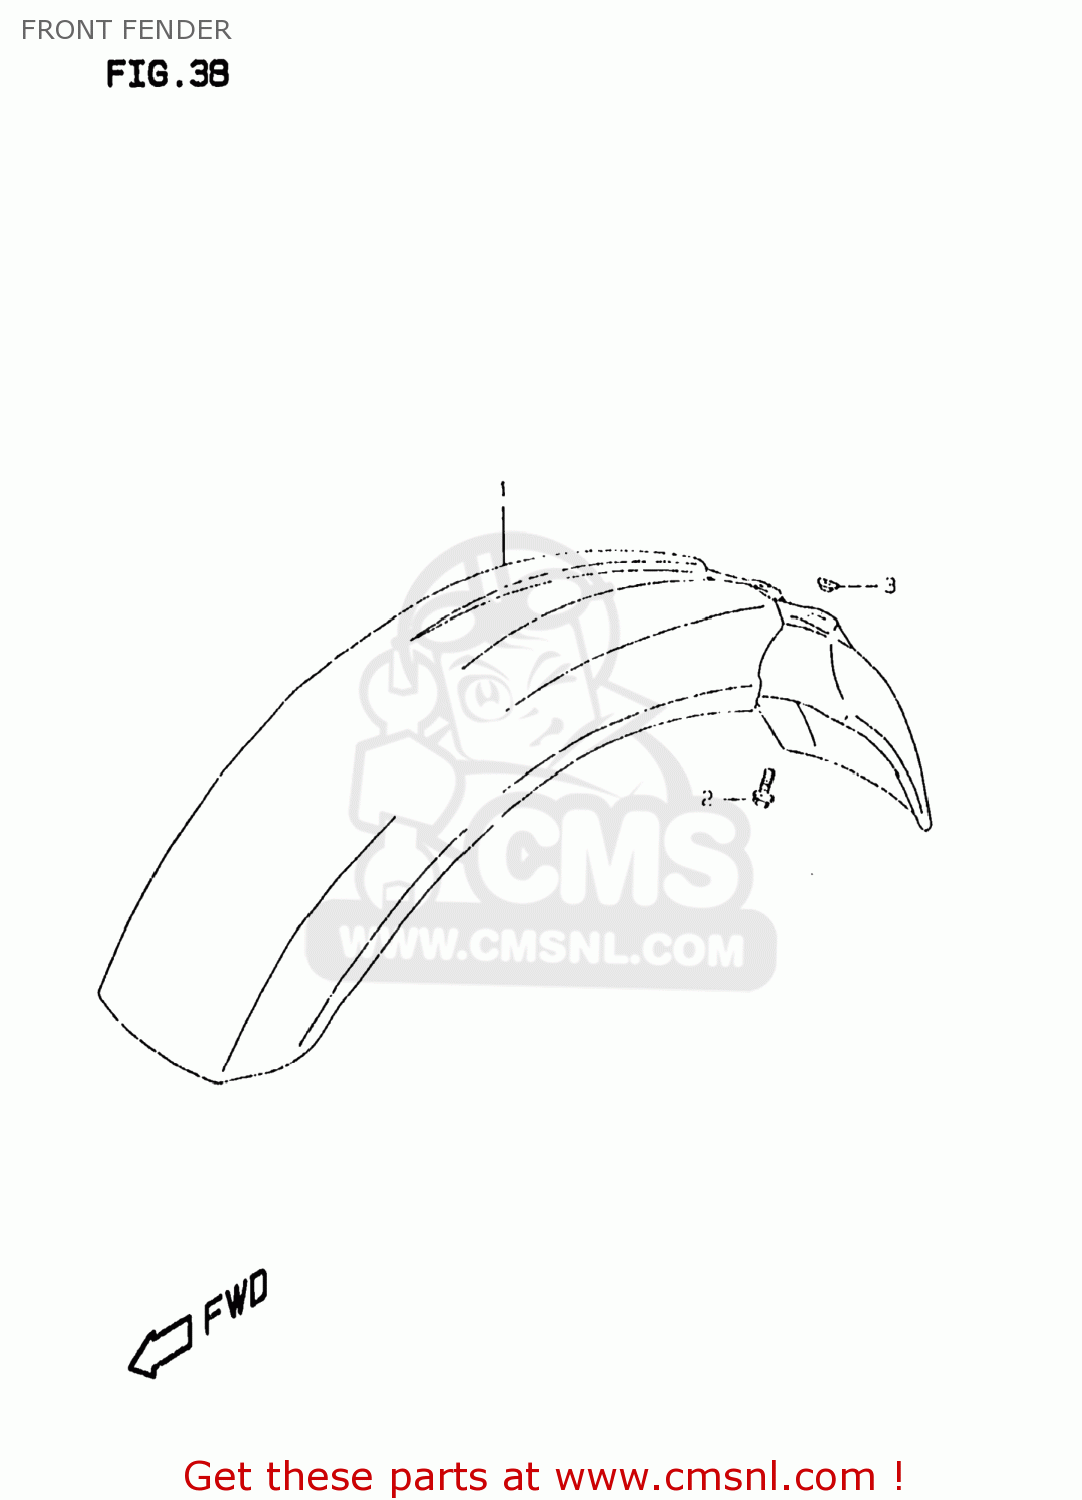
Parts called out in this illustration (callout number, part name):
1	FENDER,FR
2	BOLT(6X16)
3	WASHER
